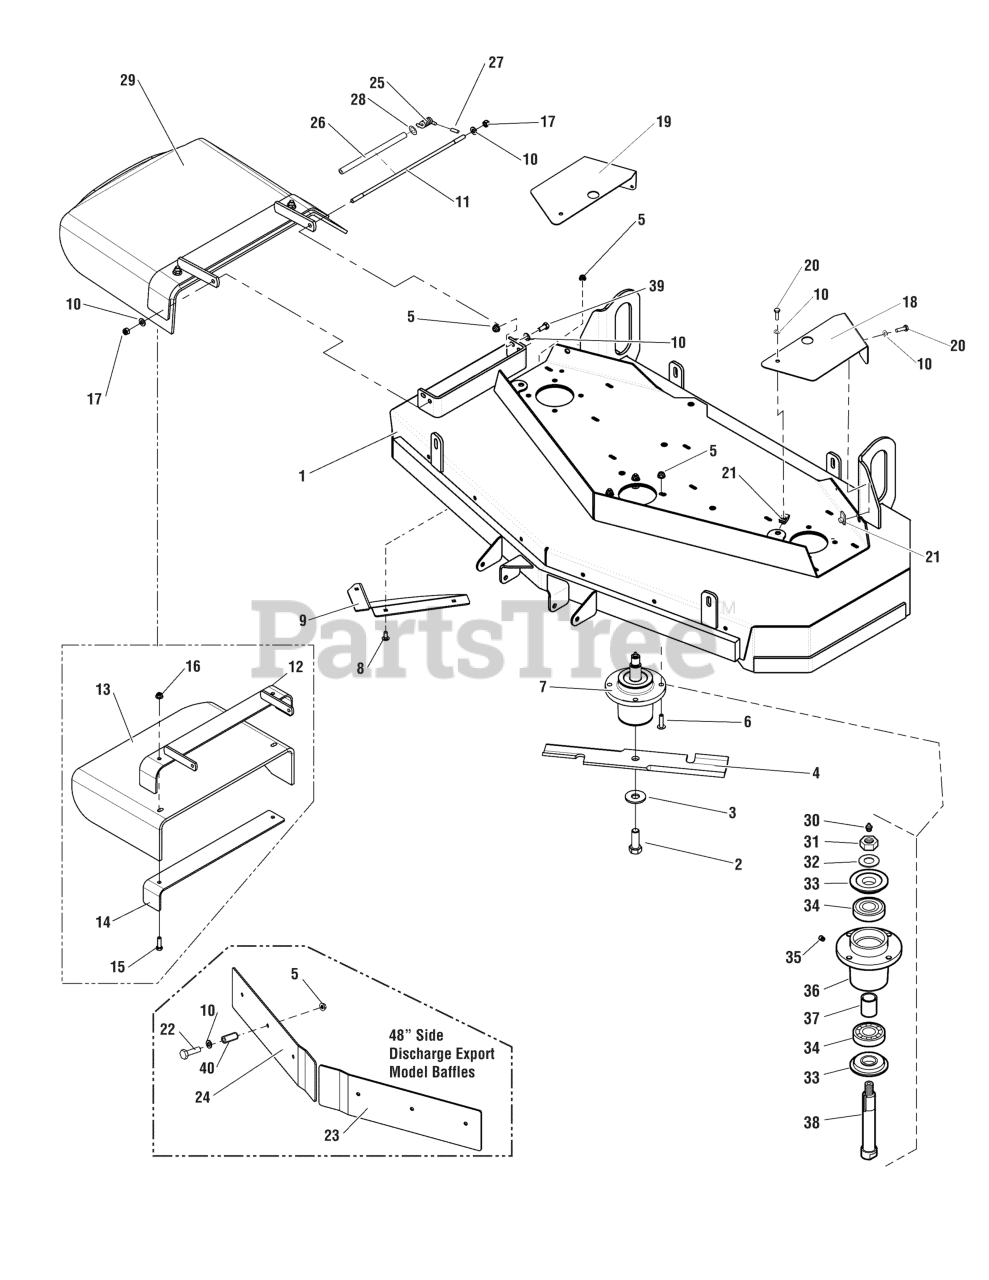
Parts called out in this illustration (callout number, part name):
1	DECK SHELL W/DECALS, 48SD, CCW CE
2	BOLT, 5/8-11 X 1-3/4 GD8
3	WASHER, 5/8 USS
4	BLADE, 16.25", SAND
5	NUT, 5/16-18 HEX NYLOCK FLANGE
6	BOLT, 5/16-18 X 1 1/4 FLANGE
7	ASSM, SPINDLE, LOW PROFILE
8	BOLT, 5/16-18 X 3/4", CARRIAGE
9	WELD, DISCHARGE BAFFLE, 48" - BLK
10	WASHER, 5/16" SAE
11	ROD, BRAKE LINKAGE
12	WELD, MOUNT, DISCHARGE CHUTE - BLK
13	CHUTE, DISCHARGE, RUBBER, 44/48/52
14	SUPPORT, DISCHARGE CHUTE, 44/48/52 - BLK
15	BOLT, 3/8-16 X 1-1/2" GD5 CZ
16	NUT, 3/8-16 HEX NYLOCK FLANGE
17	NUT, 5/16-24 HEX NYLON LOCK
18	GUARD, DECK, 48" DDS, LH - RED
19	GUARD, DECK, 48/52 DDS, RH - RED
20	BOLT, 5/16-18 X 1 GD5 YZ
21	BODY CLIP, 5/16-18-7GA MATERIAL
22	BOLT, 5/16-18 X 1-1/2 GD5
23	BAFFLE, FRONT DISCHARGE, 48 LH CCW - RED
24	BAFFLE, FRONT DISCHARGE, 48 RH CCW - RED
25	SPRING, TORSION
26	SPACER, TORSION SPRING
27	CAP, PROTECTOR, .120 ID
28	WASHER, 5/16" FENDER
29	KIT, DISCHARGE CHUTE (SV)
30	GREASE FITTING (SV)
31	NUT, 3/4-16 HEX
32	WASHER, 3/4 BELLEVILLE
33	TRASH SHIELD
34	BEARING (SV)
35	RELIEF VALVE (SV)
36	HOUSING, SPINDLE
37	SPACER, 1.00 X 1.25 X 1.75
38	SPINDLE SHAFT
39	BOLT, 5/16-18 X 3/4 GD5
40	SPACER,.32 X .50 X .75
